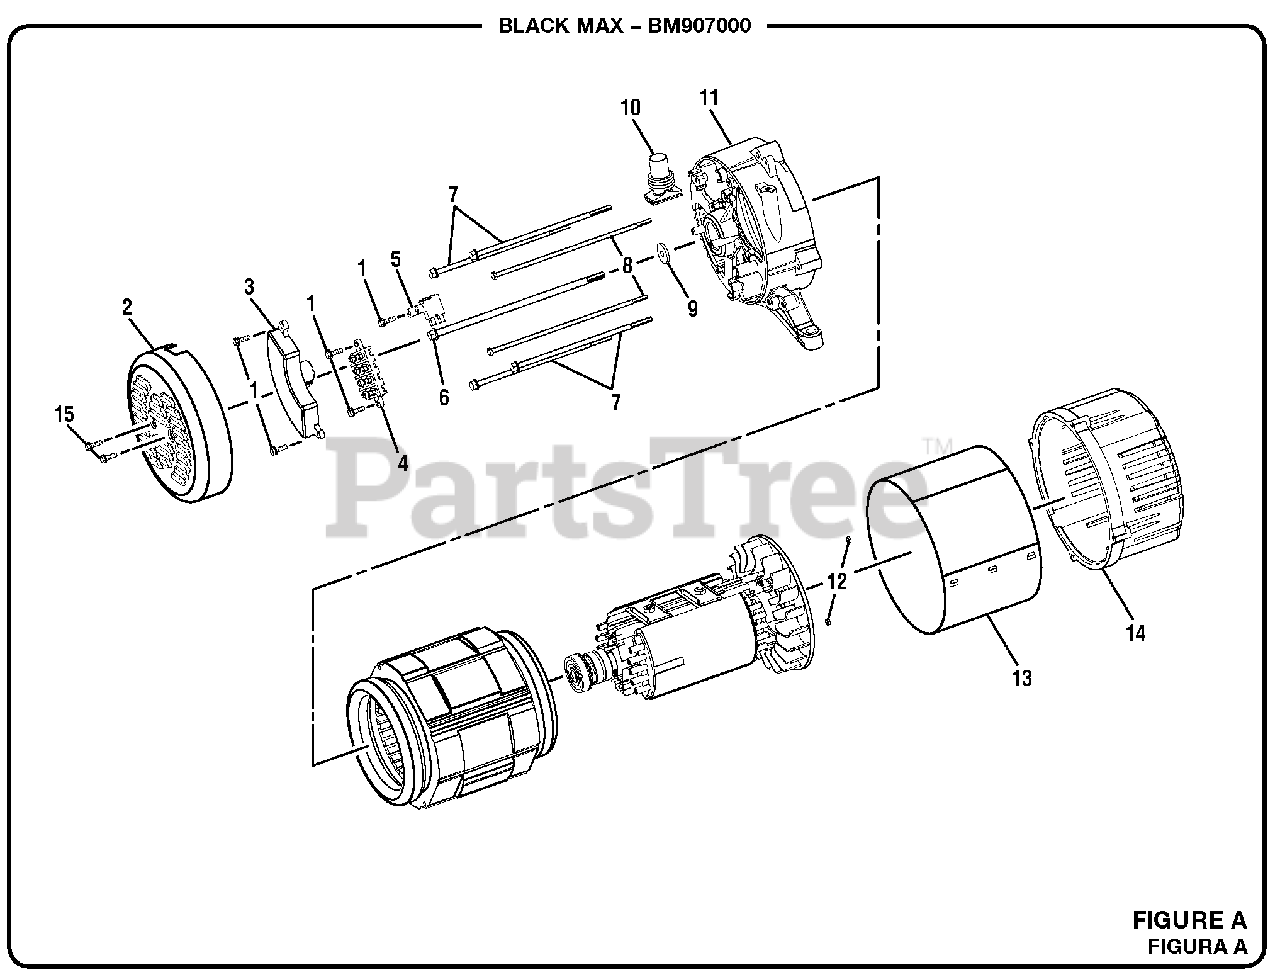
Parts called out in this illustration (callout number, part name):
1	Bolt (M5 x 16 mm, Hex Hd)
2	Brush Cover
3	Automatic Voltage Regulator
4	Terminal Block
5	Brush Assembly
6	Bolt (5/16-24 x 235 mm, Hex Washer Hd)
7	Bolt (M6 x 188 mm, Hex Washer Hd)
8	Bolt (M5 x 210 mm, Hex Washer Hd)
9	Washer (8 x 26 x 3t)
10	Rubber Boot
11	Bearing Housing
12	Hex Nut (M5)
13	Generator Head Cover
14	Adaptor Housing
15	Bolt (M5 x 12 mm, Hex Hd)
